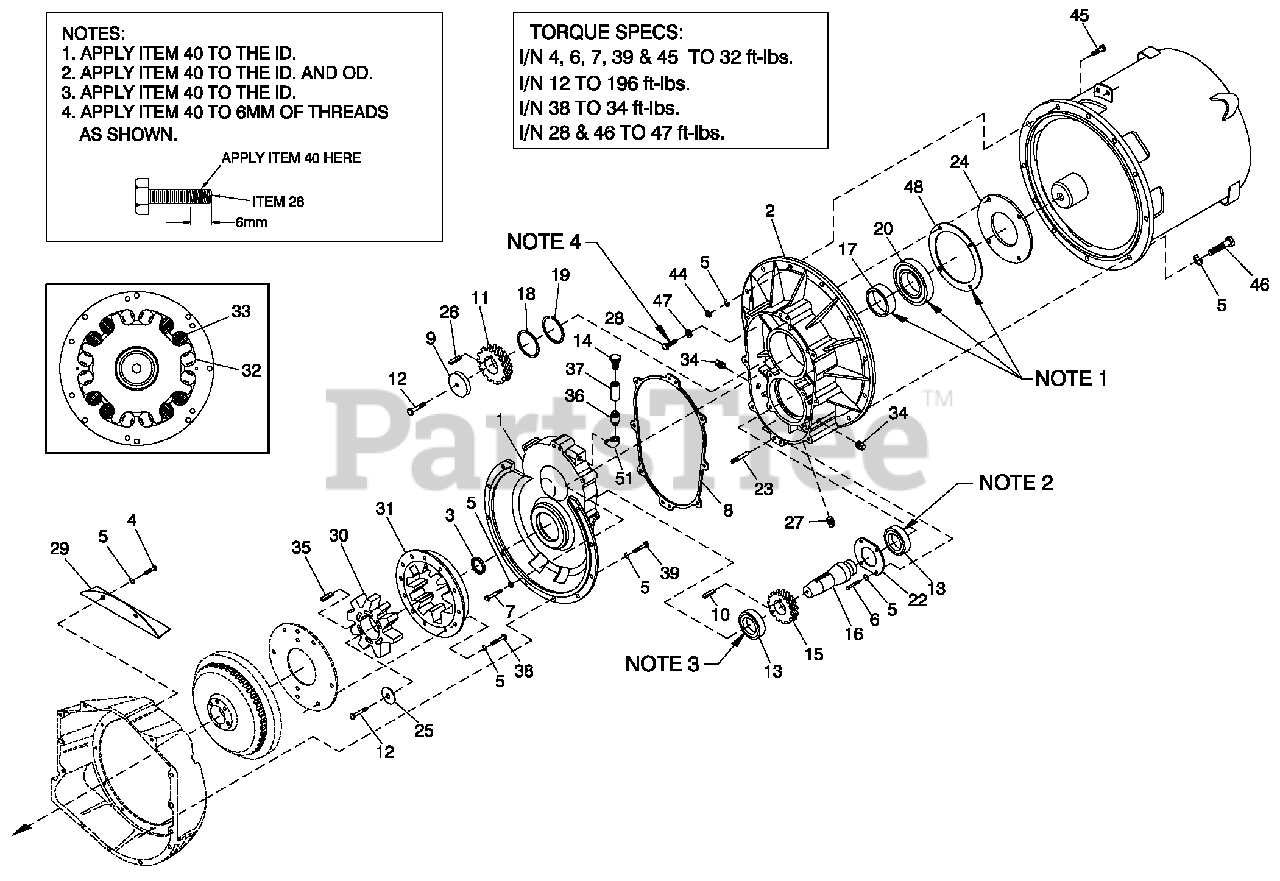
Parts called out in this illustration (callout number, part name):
1	GEAR CASE ENG. MACHINED
2	GEAR CASE ALT. MACHINED
3	SEAL OIL
4	SCREW HHC M10-1.5 X 20 G8.8
5	WASHER LOCK M10
6	SCREW HHC M10-1.5 X 25 G8.8
7	SCREW HHC M10-1.5 X 70 G8.8
8	GASKET 390 GEARBOX
9	SPACER .69 X 2.75 X .37 ST/ZNC
10	KEY 10 X 16 X 46
11	GEAR OUTPUT 1.65:1
12	SCREW HHC M16-2.0 X 35 G10.9
13	BALL BRG 65 X 120 X 23
14	BREATHER
15	GEAR INPUT 1.65: 1
16	SHAFT 390 INPUT GEAR
17	COLLAR HARDENED
18	SEAL OIL
19	SNAP RING INT 120MM
20	BEARING #6213 SEALED
22	PLATE INTRNL BRG RET
23	PIN DOWEL M8 X 24
24	PLATE BEARING THRST
25	SPACER STRESSPROOF
26	KEY 10 X 16 X 40
27	PLUG PIPE 3/8" MAGNETIC
28	SCREW HHFC M10-1.5 X 25 G10.9
29	COVER GEARBOX GUARD
30	COUPLING INNER DRAWN
31	COUPLING OUTER MACHN
32	DAMPER GB CPLR VIBRA
33	DAMPER GB CPLR VIBRA
34	PLUG STD PIPE 3/8 STEEL SQ HD
35	KEY 10 X 16 X 50
36	NIPPLE PIPE 3/8 NPT X 3-1/2
37	COUPLING FULL 3/8-18
38	SCREW HHC 3/8-16 X 1-1/2 G8
39	SCREW HHC M10-1.5 X 25 G8.8
40	RETAINING COMPOUND
44	NUT HEX M10-1.5 G8 YEL CHR
45	SCREW HHC M10-1.5 X 60 G8.8
46	SCREW HHC M10-1.5 X 40 G10.9
47	WASHER FLAT M10 SEALING COPPER
48	GASKET SEAL PLATE 390 GB
50	THREADLOCK AND SEALANT
51	ELBOW 90D STREET 3/8
